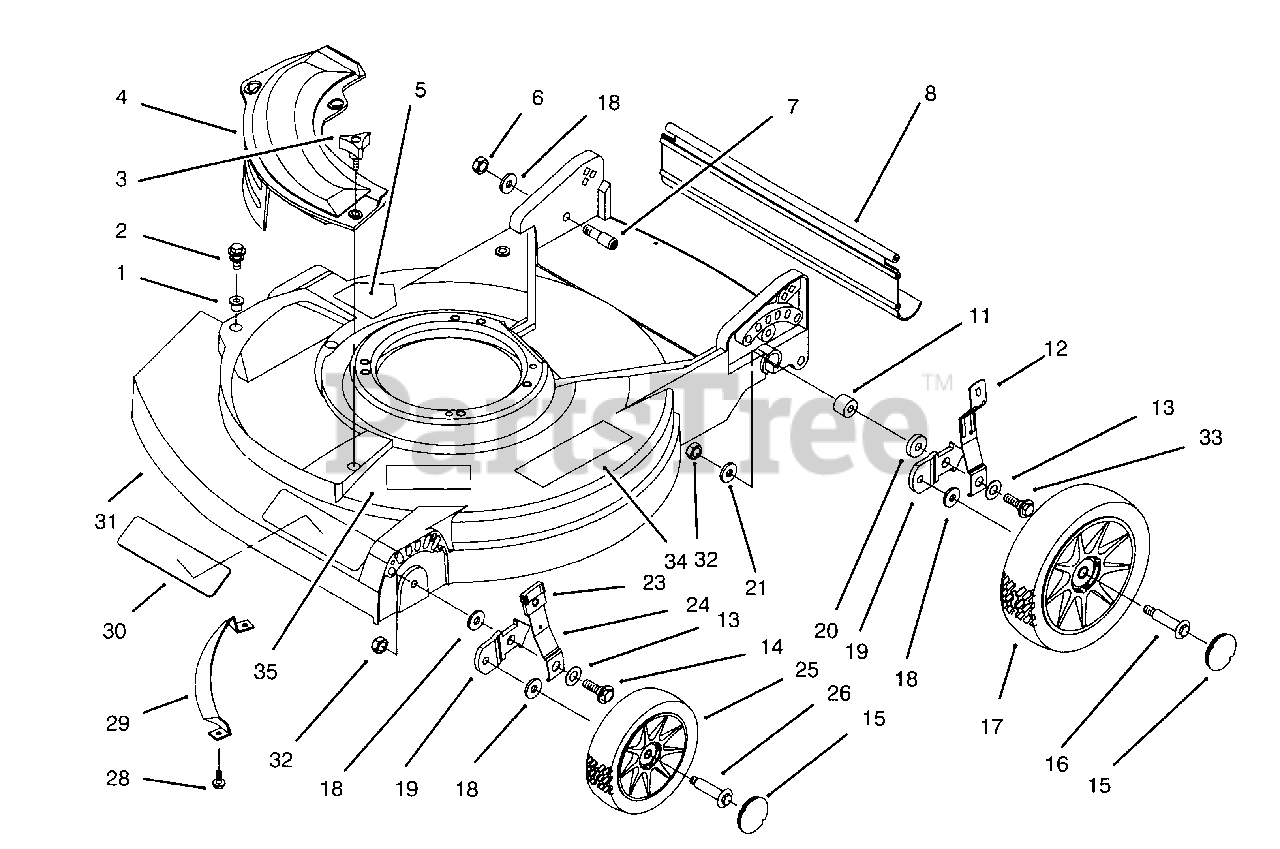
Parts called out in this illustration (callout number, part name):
1	Grommet
2	Screw-Thread Forming
3	Knob
4	Cover-Plate, Mulch
5	Decal-Danger (English)
7	Bolt-Shoulder
8	Shield-Trailing
12	Spring Arm Assembly
13	Washer-Belleville
14	Bolt-Shoulder
16	Bolt-Wheel
17	Wheel Assembly 8"
18	Washer-Wheel Bolt
19	Bracket-H. O. C.
23	Knob-Spring Arm
24	Spring Arm Assembly
25	Wheel-6"
26	Bolt-Wheel
29	Bar-Toe
30	Applique
31	Housing-21" (Incl. Ref. #5 & 30)
32	Nut-Lock
33	Bolt-Shoulder
34	Decal-Warning
35	Decal-No Rust
